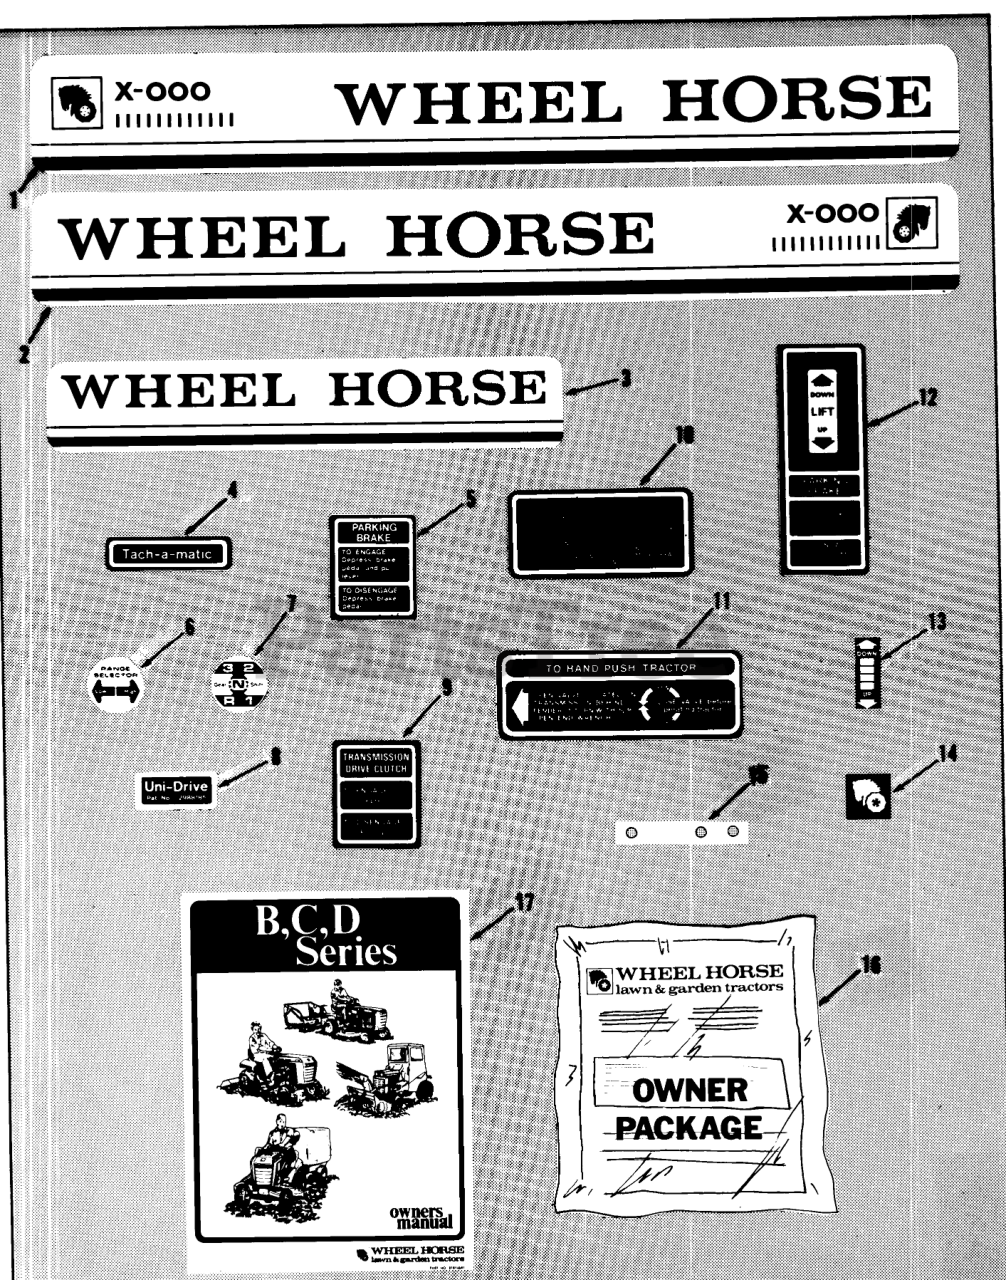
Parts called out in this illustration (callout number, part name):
1	Decal LH C-125 Automatic
1	Decal LH C-145 Automatic
1	Decal LH C-165 Automatic
1	DECAL-HOOD C-175 LH
1	Decal LH C-85 8-Speed
1	Decal LH C-105 8-Speed
1	Decal LH C-125 8-Speed
1	Decal LH C-145 8-Speed
1	Decal LH C-165 8-Speed
1	Decal LH C-175 Twin 8-Speed
2	Decal RH C-125 Automatic
2	Decal RH C-145 Automatic
2	Decal RH C-165 Automatic
2	Decal RH C-175 Twin Automatic
2	Decal RH C-85 8-Speed
2	DECAL-HOOD C-105 RH
2	DECAL-HOOD C-125 RH
2	Decal RH C-145 8-Speed
2	Decal RH C-165 8-Speed
2	Decal RH C-175 Twin 8-Speed
3	DECAL-REAR
3	Decal-Rear
4	DECAL-TACHAMATIC
5	DECAL-PARKING BRAKE
6	DECAL HI-LO
7	DECAL-SHIFT
8	Decal-Unidrive
9	Decal-Transmission Clutch
10	Decal-Maintenance
11	Decal-Push Valve
12	Decal-Parking Brake & Lift
13	Decal-Height Control
14	Decal-Hood
15	Decal-Taillight C-165, C-175 Twin Only
16	Loose Parts Package C-105, C-125 Only
16	Loose Parts Package C-145, C-165 Only
16	Loose Parts Package C-175 Twin Only
16	Loose Parts Package C-85 Only
17	TRACTOR OWNER MANUAL
